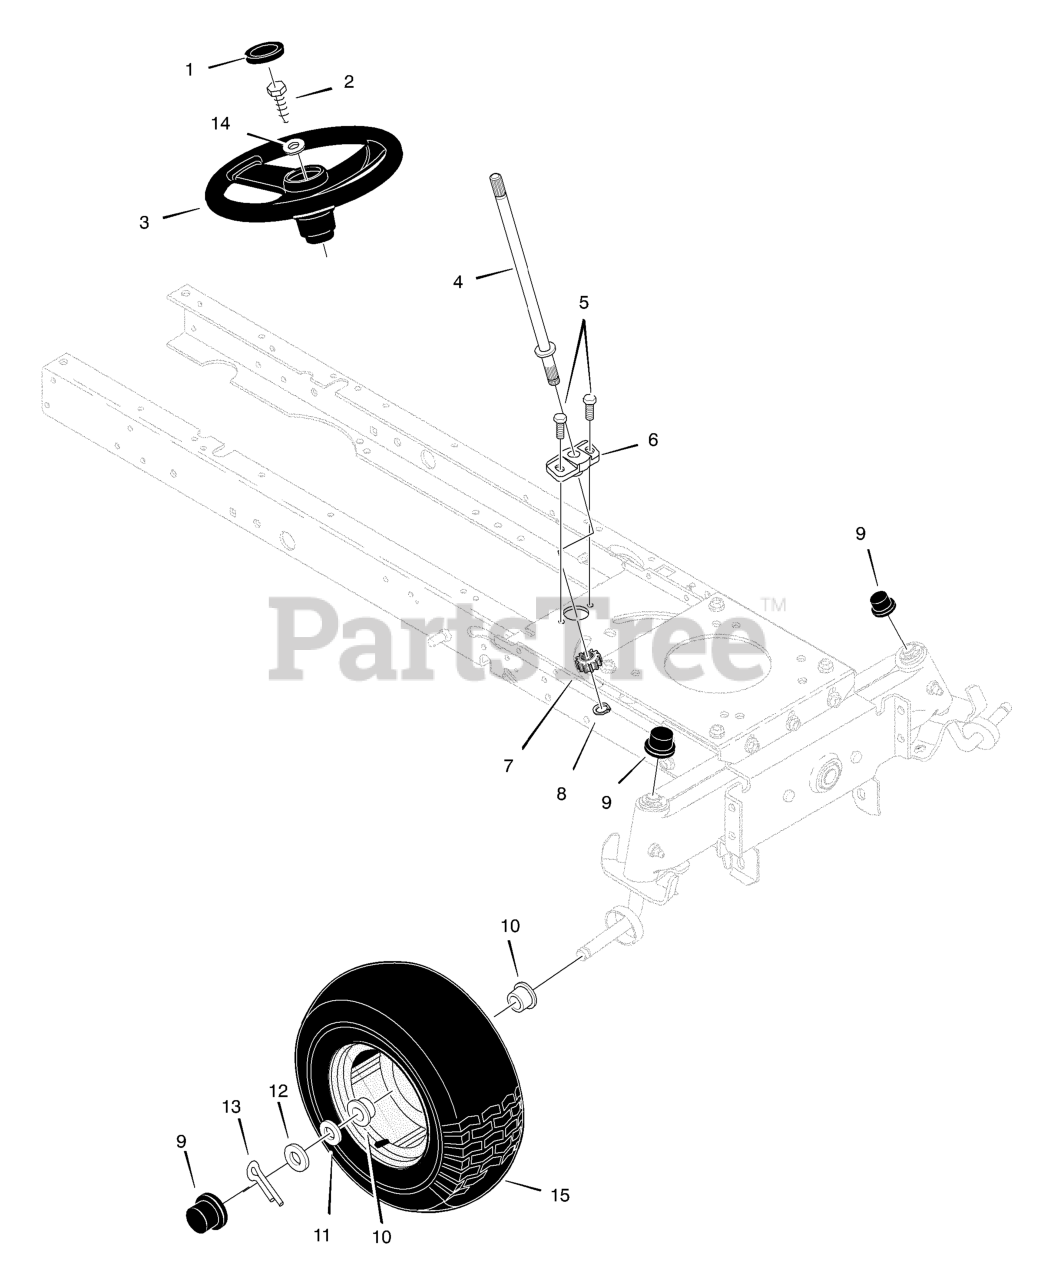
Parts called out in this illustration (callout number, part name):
2	Screw, Hex
3	Wheel, Steering
4	Shaft Assembly , Steering
6	Bearing
7	Gear, Pinion
8	Ring, Snap
10	Bearing, Wheel
13	Pin, Cotter
14	Washer
15	Wheel & Tire, Front
